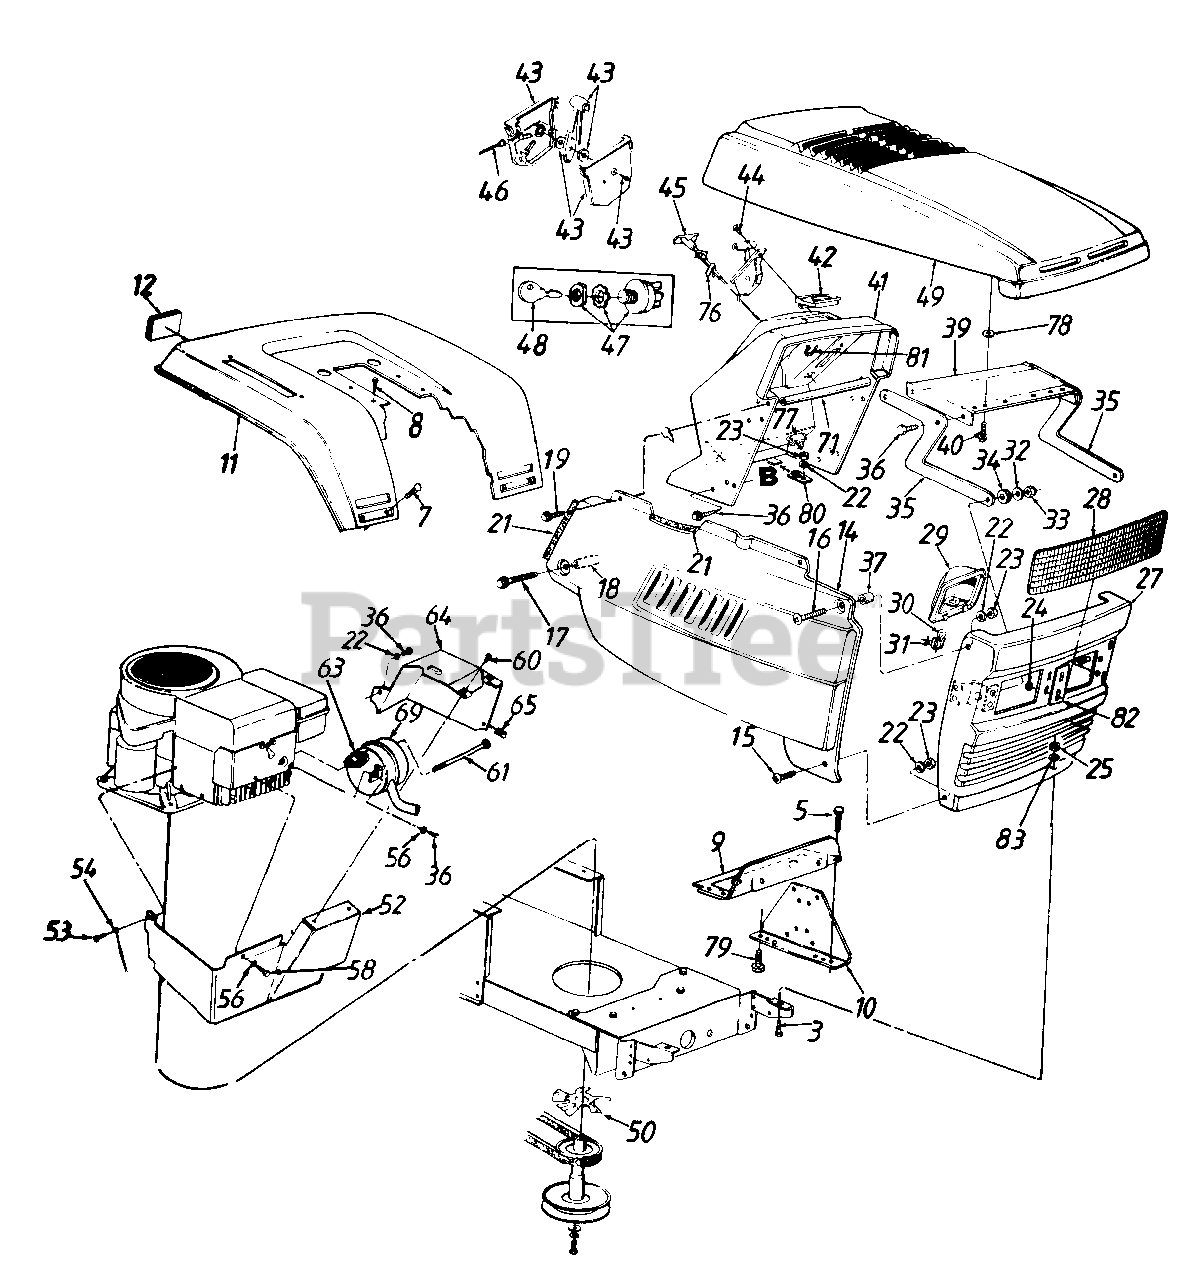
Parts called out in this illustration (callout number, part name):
3	Hex Bolt 5/16-18 x .75" Lg.
5	Hex Wash. Hd. Scr. 5/16" x .5" Lg.
7	Carriage Bolt 1/4-20 x .5" Lg.
8	Hex Wash. Hd. Tap Scr. 5/16 x .75" Lg.
16	Truss Mach. Scr. 1/4-20 x 1.0" Lg.
17	Hex Wash. TT-Tap Scr. 1/4-20 x 1.75" Lg.
18	Spacer .26" I.D. x 1.32"
19	Hex Rolling Tap Scr. 1/4-20 x .75" Lg.
21	Trim Strip - 18" Lg.
22	L-Wash. 1/4" I.D.
23	Hex Nut 1/4-20 Thd.
24	Speed Nut 5/16" Thd.
25	Hex Nut 5/16-18 Thd.
29	Headlamp Housing
30	Headlamp
31	Twist Lock Lamp Socket
32	Bell-Wash. .345" I.D. x .88"
33	Hex L-Nut 5/16-18 Thd.
34	Rubber Washer
37	Spacer .262" I.D. x .31"
41	Dash
42	Ammeter
43	Throttle Control Box Ass'y.
44	Mach. Scr. #10 x .44" Lg.
45	Choke Control 23" Lg.
46	Throttle Control Wire 18.5" Lg.
47	Ignition Switch
48	Ignition Key
49	Hood - Red
52	Muffler Heat Shield - Front
53	Truss Mach. Scr. 5/16-18 x .75" Lg.
54	Ground Wire
56	Spr. Wash. 1/4" I.D.
58	Hex Bolt 1/4-20 x 3/8" Lg.
60	Hex B-Tap Scr. #10 x .38" Lg.
61	Shoulder Bolt
63	Exhaust Gasket
64	Muffler Heat Shield - L.H.
65	Speed Nut #10-24 Thd.
69	Muffler
71	Grille Support Tube
76	Choke Retainer
77	Light Switch
78	Fl-Wash. .406" I.D x .812" O.D.
79	Hex Bolt 1/4-20 x .62" Lg.
80	Dash Fastening Tab
81	Cable Tie
82	Chrome Label
